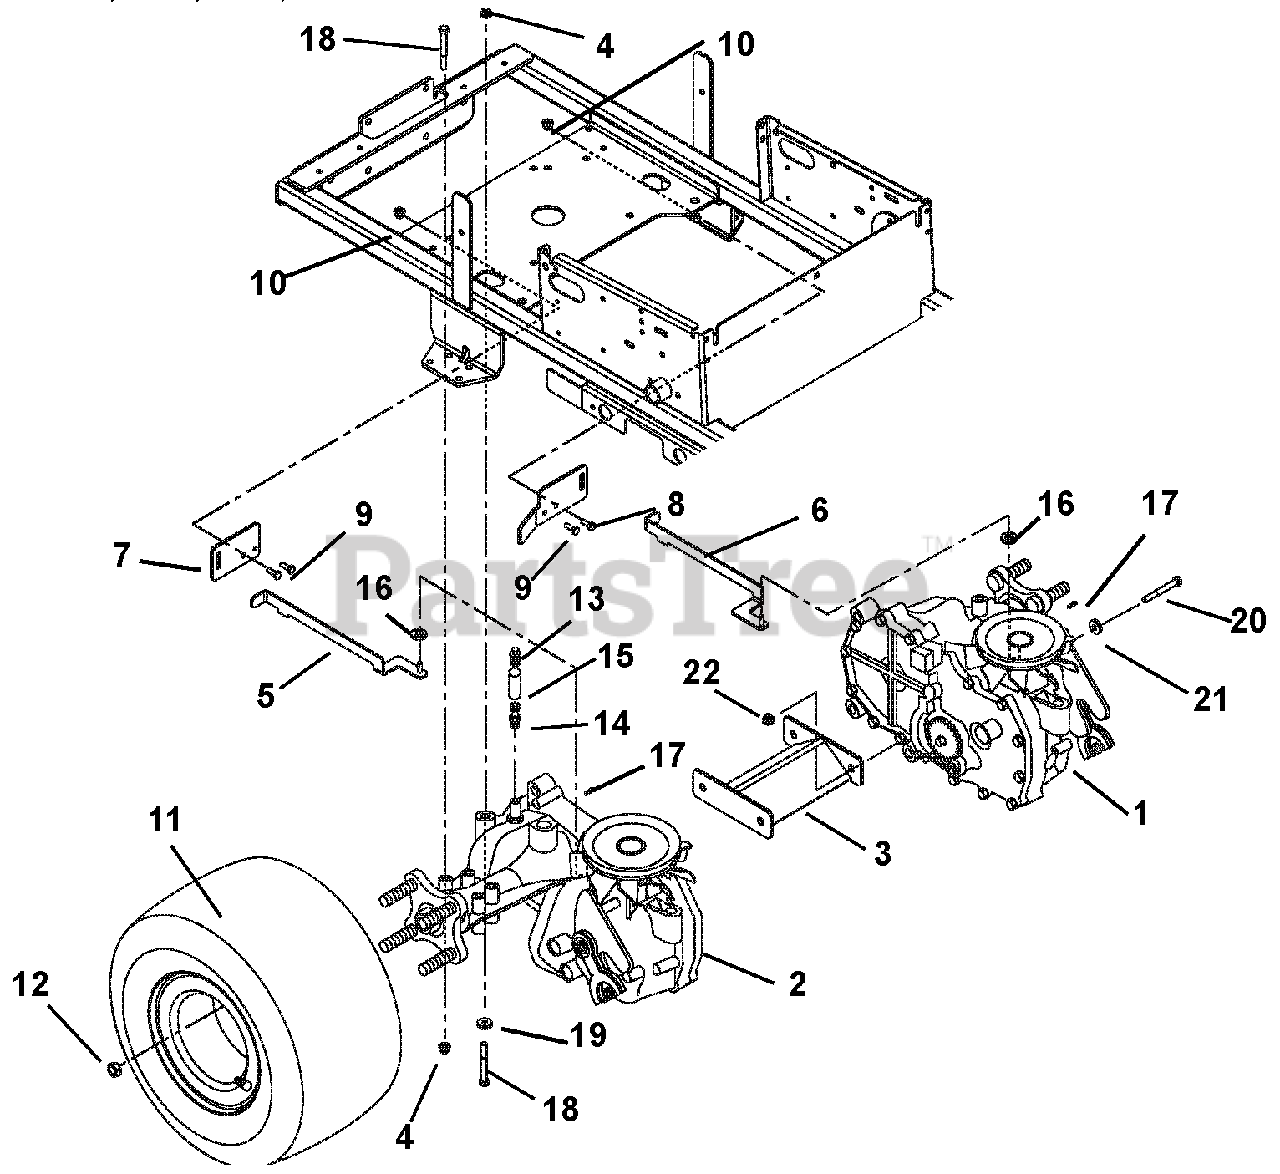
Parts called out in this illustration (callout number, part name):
1	EZT, LH TRANSAXLE (ZOOM)
1	EZT, LH TRANSAXLE (SHORT)
2	EZT, RH TRANSAXLE (ZOOM)
2	EZT, RH TRANSAXLE (SHORT)
3	WMT, TRANSAXLE SUPPORT
4	@NUT-LK-NYL-FLG .31-18 YWZC
5	WMT, DUMP VALVE (ZOOM-RH)
6	WMT, DUMP VALVE (ZOOM-LH)
7	BRACKET, DUMP VALVE
8	BRKT,DUMP VALVE/CLUTCH STOP
8	CLUTCH STOP
9	@BLT-HEX .25-20X.75 GR5 YWZC
10	NUT-LUG .50-20 YWZC
11	TIRE/WHEEL ASSY, 18X9.50-8 OFF
11	TIRE/WHEEL ASSY, 18X8.50-8 CTR
11	TIRE/WHEEL ASSY, 18X6.5-8 CTR
12	NUT-LUG .50-20 YWZC
13	CAP-VENT .50
14	FTG-STR .50 O-RING
15	HOSE - VENT
16	WSHR-FL-STL .265X.50X.087YWZC
17	PIN-HAIR INT .06X.18X.77
18	@BLT-HEX .31-18X2.75 GR5 YWZC
19	WSHR-FL-STL .328X.87X.179 YWZC
20	@BLT-HEX .38-16X2.50 GR5 YWZC
21	WSHR-FL-STL .406X1.00X.188 YWZ
22	@NUT-LK-NYL-FLG .38-16 YWZC
